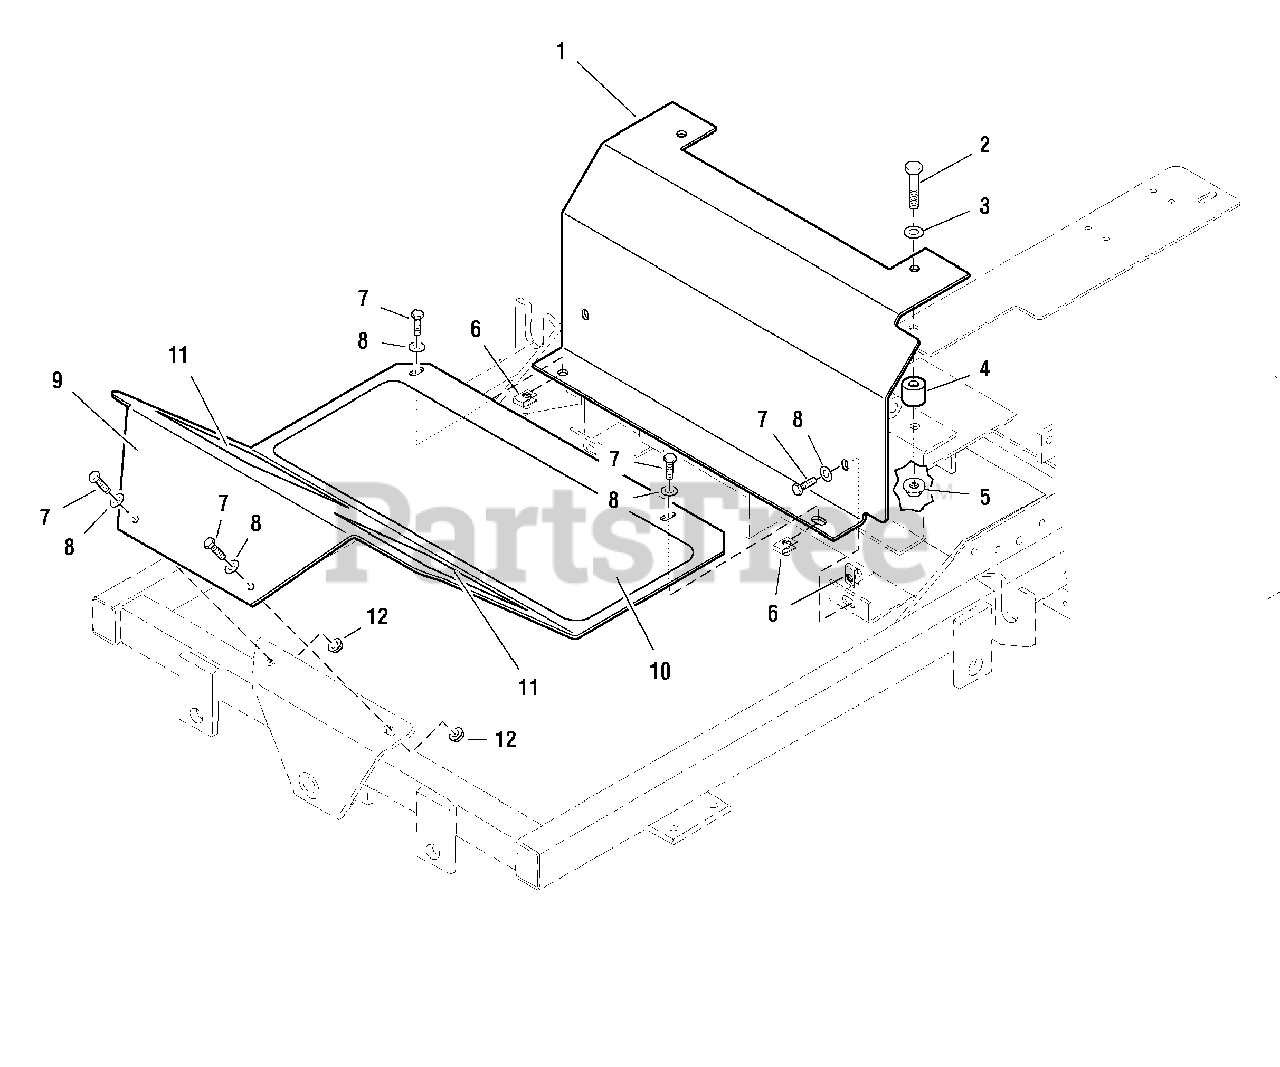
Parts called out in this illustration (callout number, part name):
1	BRAKE COVER PANEL
2	CAPSCREW, Hex Hd, 3/8-16 x 2
3	WASHER, 3/8
4	SPACER, .39 x 1.00 x .88
5	NUT, Hex, Serrated Flange, 3/8-16
6	BODY CLIP, 5/16-18
7	CAPSCREW, Hex Hd, 5/16-18 x 1
8	WASHER, 5/16
9	FLOOR PLATE
10	SAFETY WALK
11	SAFETY WALK
12	NUT, Hex, Serrated Flange, 5/16-18
